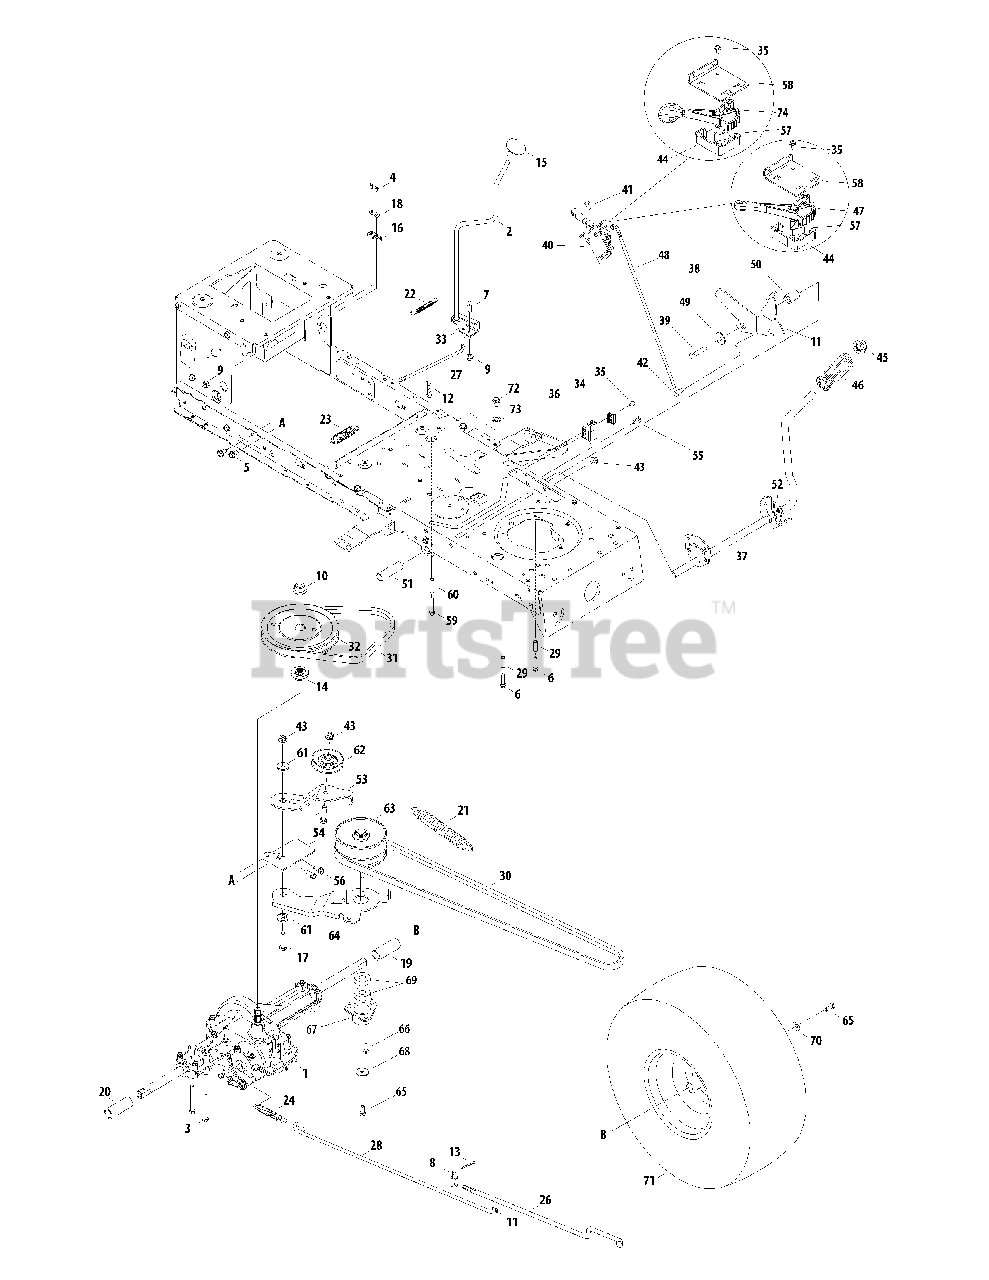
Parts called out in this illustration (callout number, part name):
1	Transmission Ass’y
2	Shift Lever Ass’y
3	Hex Scr 5/16-18 x 2.75
4	Hex Wash HD AB S-Tapp Scr #8-.50
5	S-Tapp Scr 5/16-18 x .75
6	Hex Bolt 1/4-20 x 1.25
7	Hex Bolt 5/16-18 x .75" Lg. Gr. 5
9	Flange Locknut 5/16-18 Gr. F, Ny lon
11	Cotter Pin 3/32 dia x 1.00 Lg.
13	Bow Tie Cot ter Pin
14	Pulley Hub 5/8" Spline
16	Short Spring Switch
17	Screw, 3/8-16 x 1.75
18	Insulator Nut Plate
19	Sleeve, .758 x .821 x 3.3125
20	Sleeve, .758 x .821 x 2.4375
21	Spring, Exten sion, 1.15 OD x 7.90
22	Spring, Exten sion
23	Spring, Exten sion, .80 OD x 3.28
24	Ext. Spring .59 OD x 4.00 Lg.
25	Flat Washer .344 ID x .625 OD x .063
26	Control Rod, Variable Speed
29	Spacer .260 x .375 x 1.030 Lg.
31	Belt
32	Pulley, V-Type, 7.25 dia.
33	Shift Bracket, Adjustable
34	Switch Plate
35	Hex AB-Tap Scr #10 X .50" Lg.
36	Interlock Switch
37	Drive Pedal Assembly
38	Latch Ass’y, Engage ment (RMC)
39	Hex Screw 3/8-16 x 1.875 Gr. 5
40	6 Speed Shift Control Ass'y
40	7 Speed Shift Control Ass'y
40	7 Speed Shift Control Ass'y (Troy Bilt)
41	Screw, 1/4-20 x .5
42	Adjustment ferrule
43	Flange Lock-Nut 3/8-16 Gr. F Ny lon
44	Control Cover
45	Push Cap 5/8" Dia Rod
46	Foot Pad
47	Shift Lever - 6 Speed
47	Shift Lever - 7 Speed
48	Speed Selecter Control Rod
49	Flat Washer .411 ID x 1.25 OD x .10
50	Flange Spacer .390 x .671 x 1.095
51	Spacer .630 ID
52	Pedal Support Bracket
53	Idler Bracket
54	Transmission Torque Bracket
55	Self-tap ping Screw 5/16-18 x .625
56	Hex Wash. Hd. Scr. 5/16-18 x .75 Lg.
57	Shift Lever Spring
58	Control Bracket
59	Screw, 1/4-20 x 1.625
60	Spacer, .260 x .372 x 1.420
61	Shoulder Spacer
63	Variable Speed Pulley Ass’y 4.75 OD
64	Variable Speed Bracket Ass’y
65	Hex L-Screw 5/16-24 x 0.75 Gr. 5
66	Hex Scrw 1/4-20 x 1.5
68	Flat Washer .22 ID x 1.25
69	Ball Bearing 17 x 40 x 12
70	Cupped Washer .345 ID x .88 OD x .060
71	Wheel Assembly Complete, 20 x 8 x 8
71	Tire Only, 20 x 8 x 8, Square Shoul der
72	Hex Wash S-Tapp Scr 1/4-20 x .50
73	Lockwasher 1/4"
74	Shift Lever (spoon style) - 7 Speed
